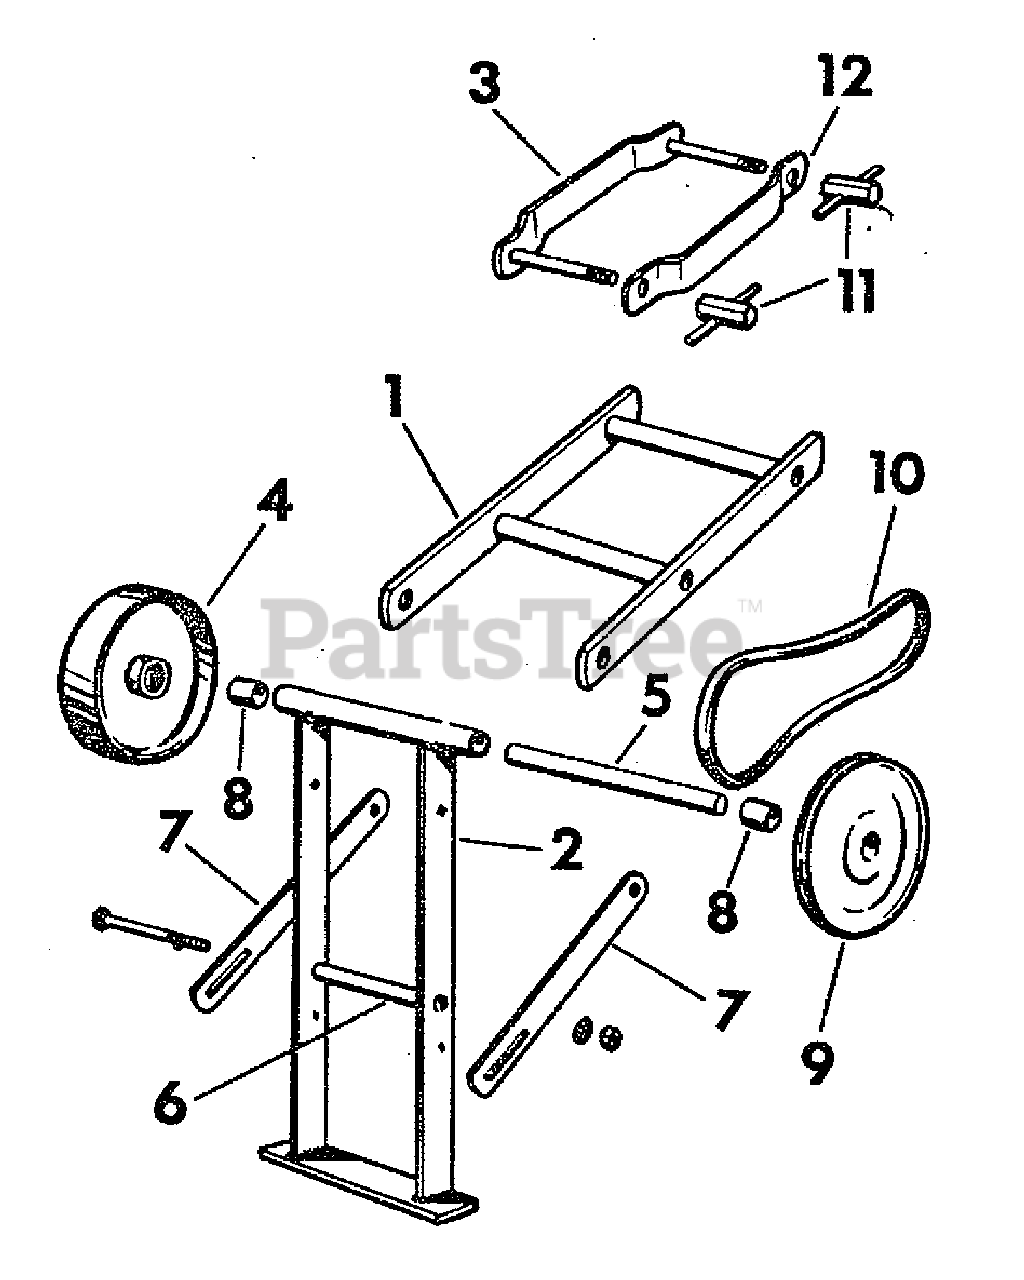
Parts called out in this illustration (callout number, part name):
2	BEARING BRACKET
3	CLAMP, Hitch
5	COUNTERSHAFT
9	SHEAVE, Transmission
10	BELT, "V"
11	NUT, Wing, Complete
12	SIDE PLATE, Hitch
